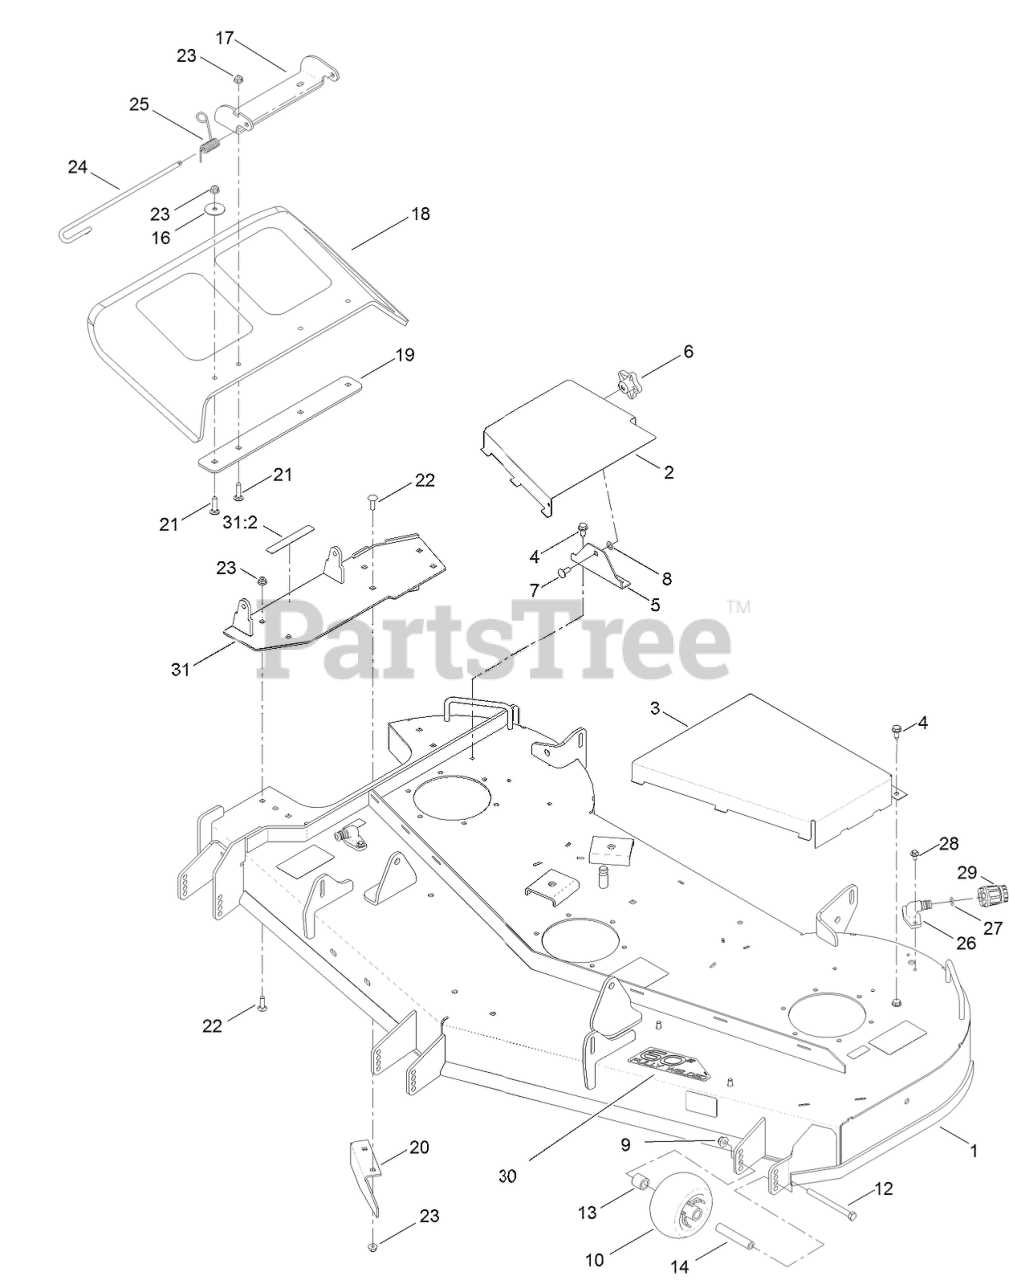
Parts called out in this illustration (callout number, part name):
1	60 INCH DECK ASM
2	COVER-BELT, RH
3	COVER-BELT, LH
4	SCREW-HWHTF
5	BRACKET-SUPPORT
6	KNOB-HANDLE
7	SCREW-CARR
8	RING-RETAINING, BOLT
9	NUT-HF, NI
10	ROLLER-SCALP, ANTI
12	SCREW-HH
13	SPACER-AXLE, REAR
14	TUBE-SPANNER
16	WASHER-FLAT
17	BRACKET-DEFLECTOR, UPPER
18	DEFLECTOR
19	PLATE-DEFLECTOR
20	BAFFLE-CUTOFF
21	SCREW-CARR
22	SCREW-CARR
23	NUT-HF, NI
24	PIN-CHUTE
25	SPRING-TORSION
26	FITTING-WASHOUT
27	O-RING
28	SCREW-HHFTF
29	CONNECTOR-HOSE
31	PIVOT-DEFLECTOR
31:2	DECAL-DANGER
